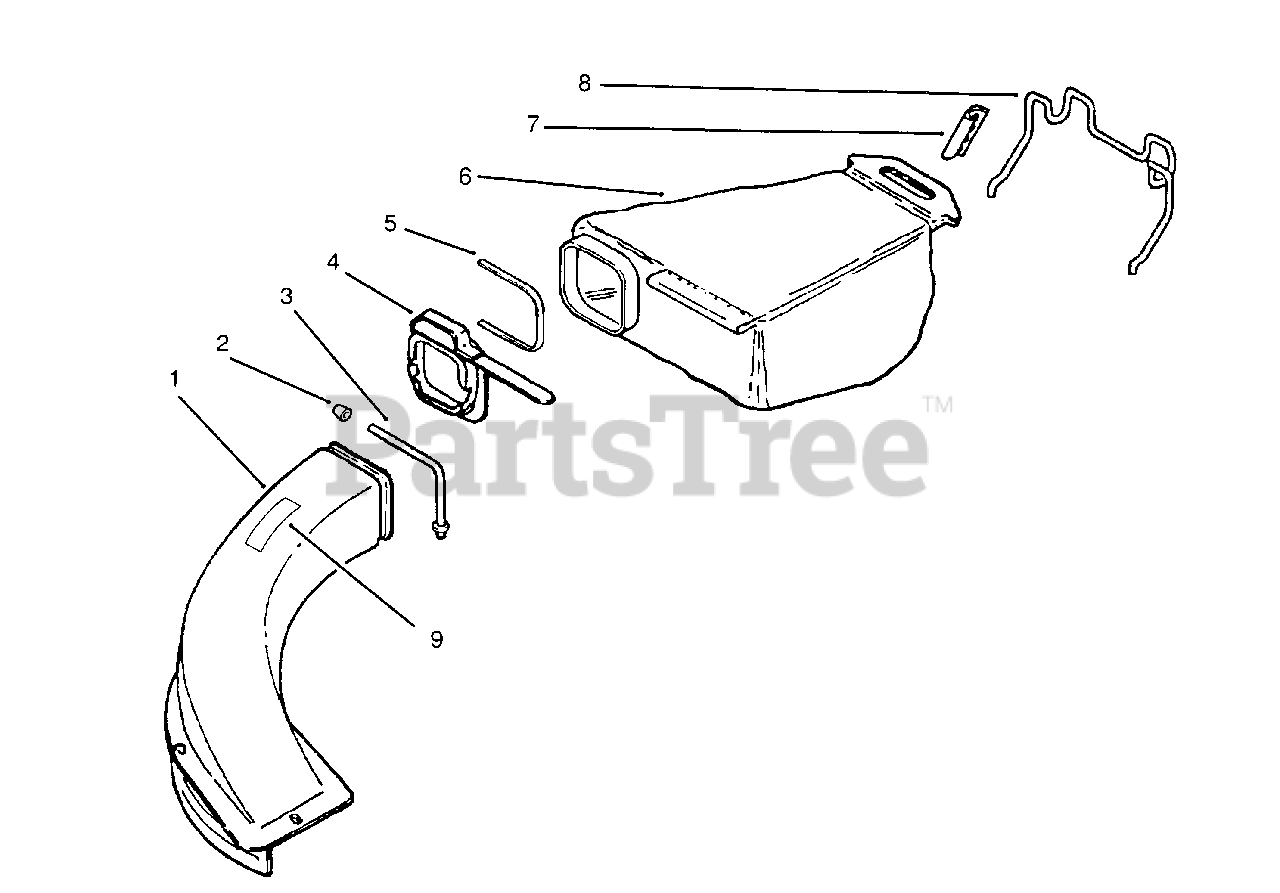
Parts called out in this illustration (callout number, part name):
1	Chute & Support Assembly (Incl. Ref. # 2, 3 & 9)
2	Nut-Cap
3	Chute Support
4	Adaptor Assembly
5	Tie Strap
6	Bag Assembly
7	Hanger Clamp
8	Wide Hanger
9	Decal-Danger
